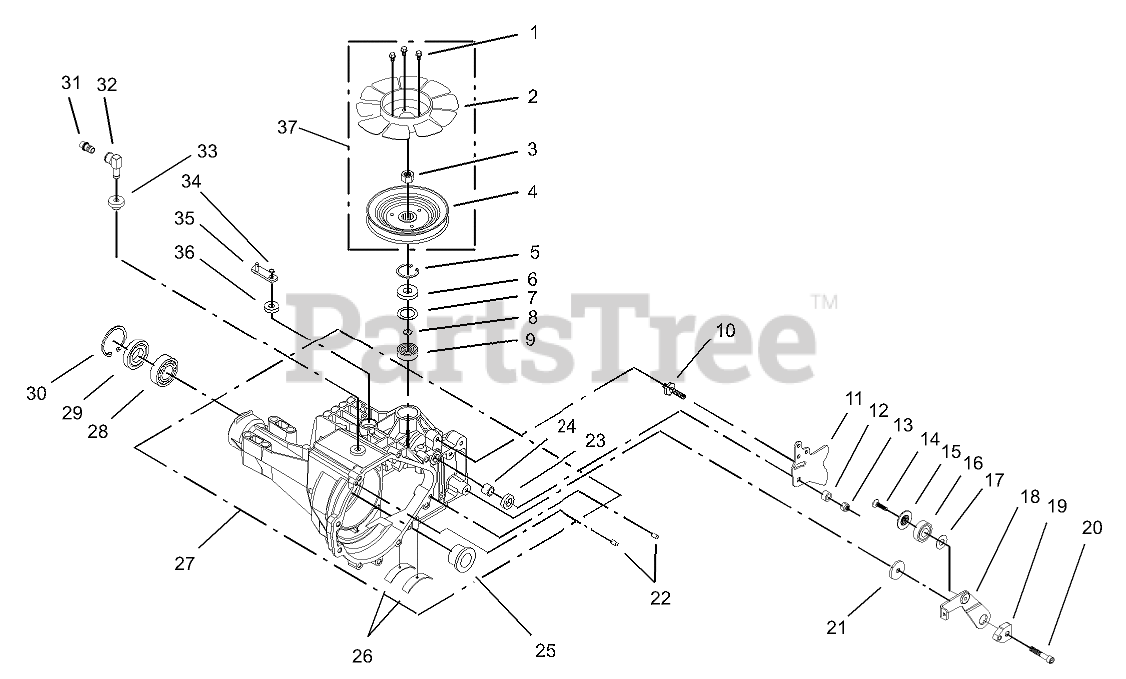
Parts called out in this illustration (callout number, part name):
3	NUT-HEX
4	PULLEY
5	RING-RETAINING
6	SEAL-LIP
7	SPACER
8	RING-WIRE, RETAINING
9	BEARING-SHAFT, BALL
11	ARM-CONTROL
12	SPACER-TRUNNION
13	NUT-HEX, LOCK
14	SCREW-COUNTERSUNK
15	SPACER-LOCATING
16	BEARING
17	WASHER
18	ARM-RETURN
19	PUCK-ADJUSTING
21	WASHER
23	SEAL-LIP
24	BUSHING-TRUNNION
25	BEARING-FLANGE
26	BEARING-CRADLE
27	MAIN HOUSING ASM
28	BEARING-BALL
30	RING-RETAINING
31	VENT CAP ASM
32	FITTING
33	BUSHING-RUBBER
34	RING-RETAINING
35	ARM-BYPASS
36	SEAL-LIP
37	FAN/PULLEY KIT
